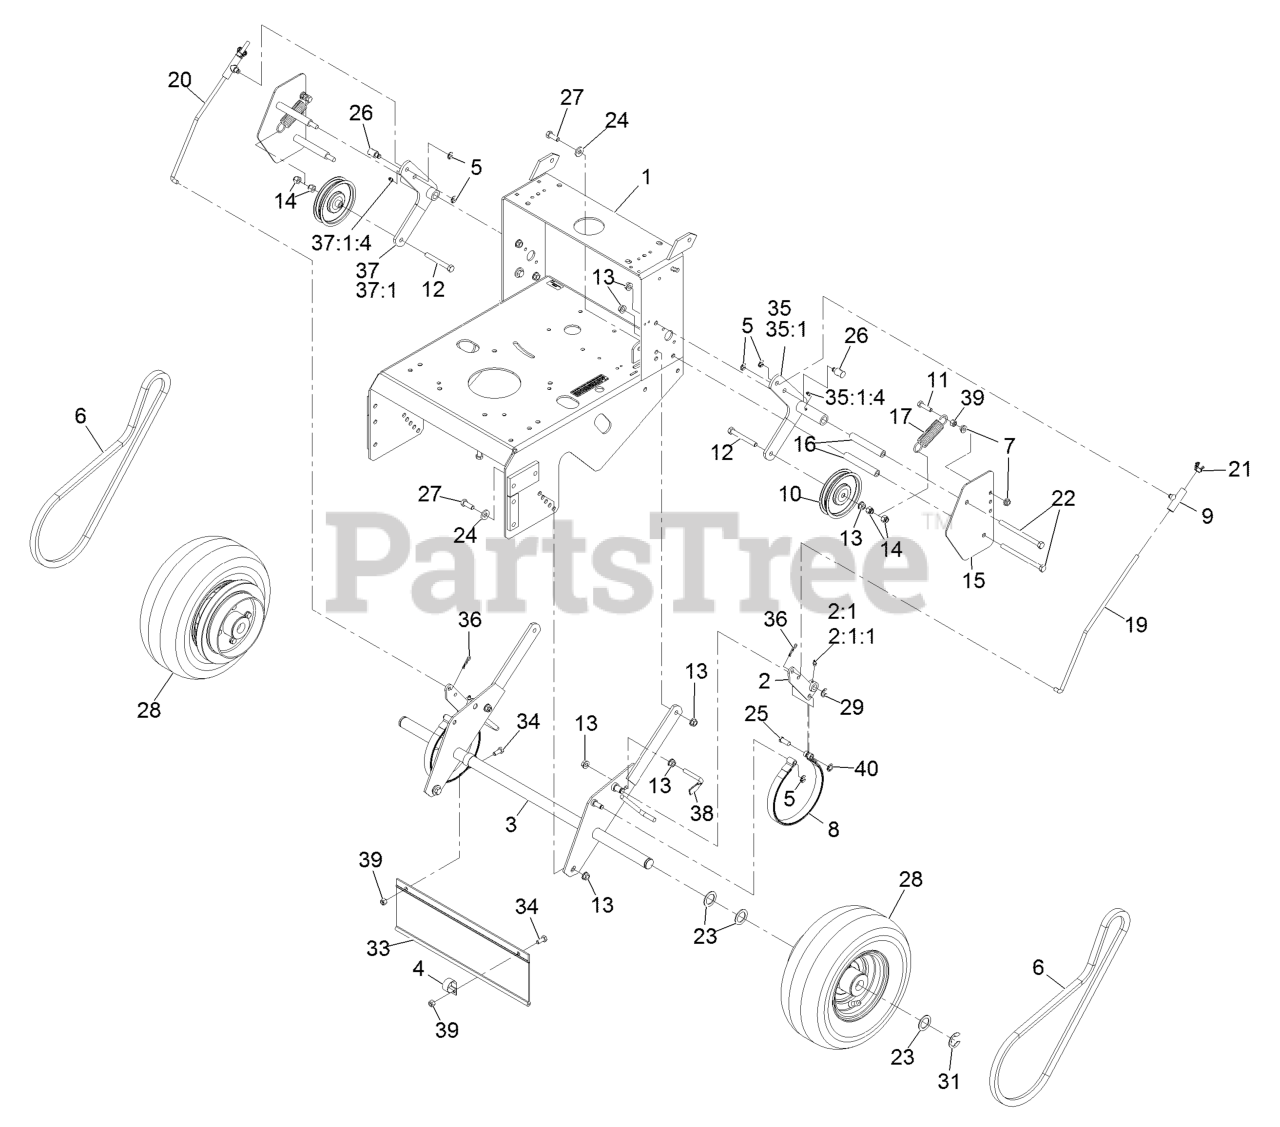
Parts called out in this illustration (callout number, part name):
1	ASM, METRO ENGINE DECK W/
2	ARM-BRAKE
2:1	Wld,Brake Arm
2:1:1	ASM,BUSHING/ZERK
4	CLAMP-R
5	RING-RETAINING
6	BELT,WHEEL DRIVE
8	BAND-BRAKE
9	SWIVEL-BRAKE
10	IDLER-WHEEL, DRIVE
11	SCREW-HH, SPECIAL
12	SCREW-HH
13	NUT-HHF, WHIZ
14	NUT-LOCK, NI
15	SHIELD-WHEEL, DRIVE
16	SPACER-SHIELD
17	SPRING-EXTENSION
19	LINKAGE-BRAKE, LH
20	LINKAGE-BRAKE, RH
21	WINGNUT-NYLOCK
22	SCREW-HH
23	WASHER-SPACER
24	WASHER-BELLEVILLE
25	PIN-CLEVIS
26	SWIVEL-DRIVE LEVER, 3/8 L
27	SCREW-HH
28	DRIVE WHEEL ASM
29	RING-RETAINING, EXTERNAL
31	RING-SNAP
33	SHIELD-TRAILING
34	SCREW-HH
35	ARM-IDLER, LH
35:1	Idler Arm LH Assy
35:1:4	FITTING-GREASE
36	PIN-COTTER
37	ARM-IDLER, RH
37:1	Idler Arm RH Assy
37:1:4	FITTING-GREASE
38	SCRAPER
39	NUT-LOCK, NI
40	RING-RETAIN,PUSH,EXT,FLAT
